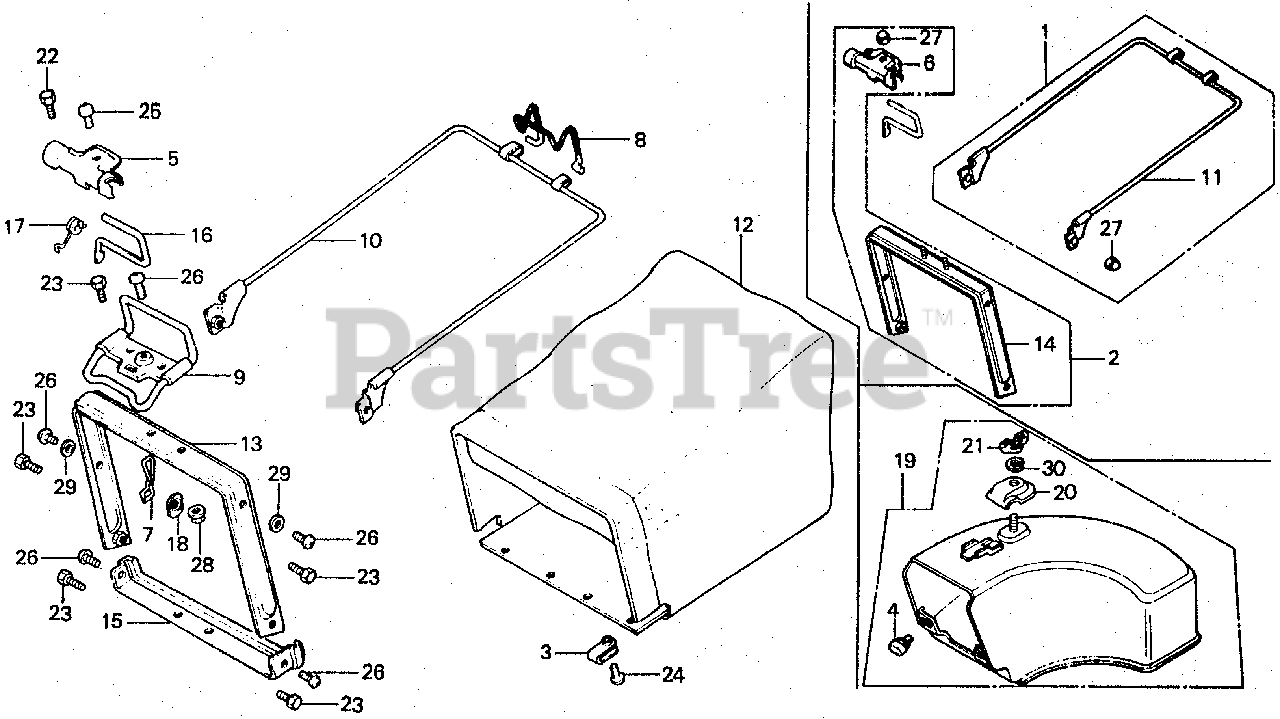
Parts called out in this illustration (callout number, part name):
1	BAR, GRASS CATCHER KIT (NOT AVAILABLE)
2	FRAME KIT A, BAG
3	NUT, CLIP (SOURCE: VINTAGE PARTS INC.)
4	STOPPER, DISCHARGE GUARD
5	FRAME KIT A, BAG
5	PLATE, HINGE BAG
6	PLATE, HINGE BAG (NOT AVAILABLE)
7	HOOK, BAG SET
8	GRIP, GRASS BAG
9	HANDLE, FR. GRASS BAG
10	BAR, GRASS BAG
11	BAR, GRASS BAG (NOT AVAILABLE)
12	FABRIC, GRASS BAG
13	FRAME A, BAG
14	FRAME A, BAG
15	FRAME B, BAG
16	LEVER, LOCK BAG
17	SPRING, LOCK LEVER RETURN
18	NUT, HOOK HOLDER
19	ADAPTER, DISCHARGE *NH2M*
20	PLATE, CLAMP
21	WINGNUT, TOOL BOX SETTING
22	BOLT, HEX. (6X8)
23	BOLT, HEX. (6X12)
24	SCREW, PAN (5X8)
25	SCREW, PAN (6X8)
26	SCREW, PAN (6X12)
27	NUT, CAP (6MM)
28	NUT, FLANGE (6MM)
29	WASHER, PLAIN (6MM)
30	WASHER, SPRING (6MM)
